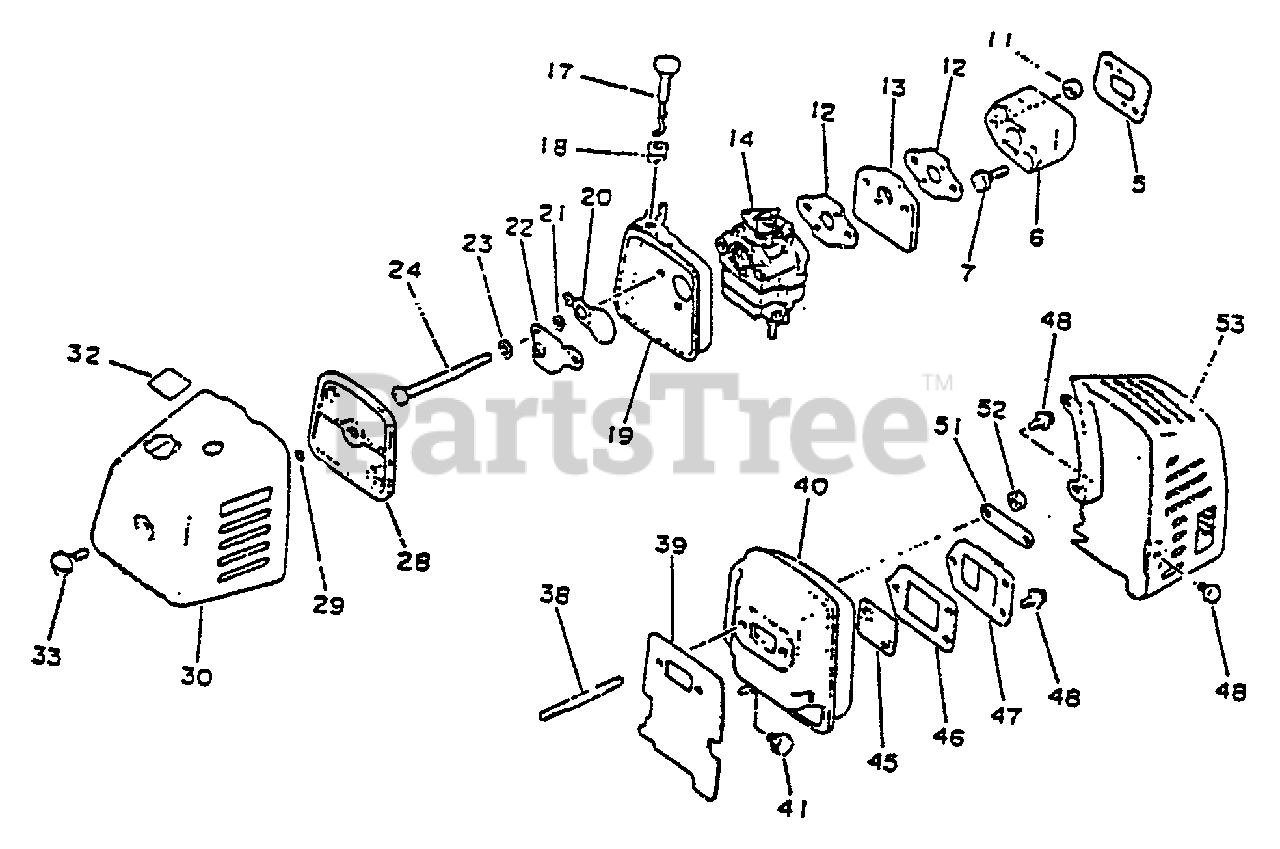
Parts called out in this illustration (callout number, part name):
5	GASKET
6	INSULATOR
7	SCREW 5×20
11	NUT M5
12	GASKET, INTAKE
14	CARBURETOR - WY-18
17	ROD, CHOKE
18	GROMMET, CHOKE
19	CASE, AIR FILTER
20	SHUTTER, CHOKE
21	WASHER 5.2×8×0.8T
23	WASHER, SPRING 5
24	SCREW - 5×60
28	FILTER, AIR
30	AIR FILTER COVER ASSY
32	LABEL, CHOKE
38	BOLT, STUD
39	GASKET
41	SCREW 5×10
45	SCREEN, SPARK ARRESTER
46	GASKET, EXHAUST
47	LID, MUFFLER
48	SCREW 4×10
52	NUT, LOCK M5
53	COVER, EXHAUST
